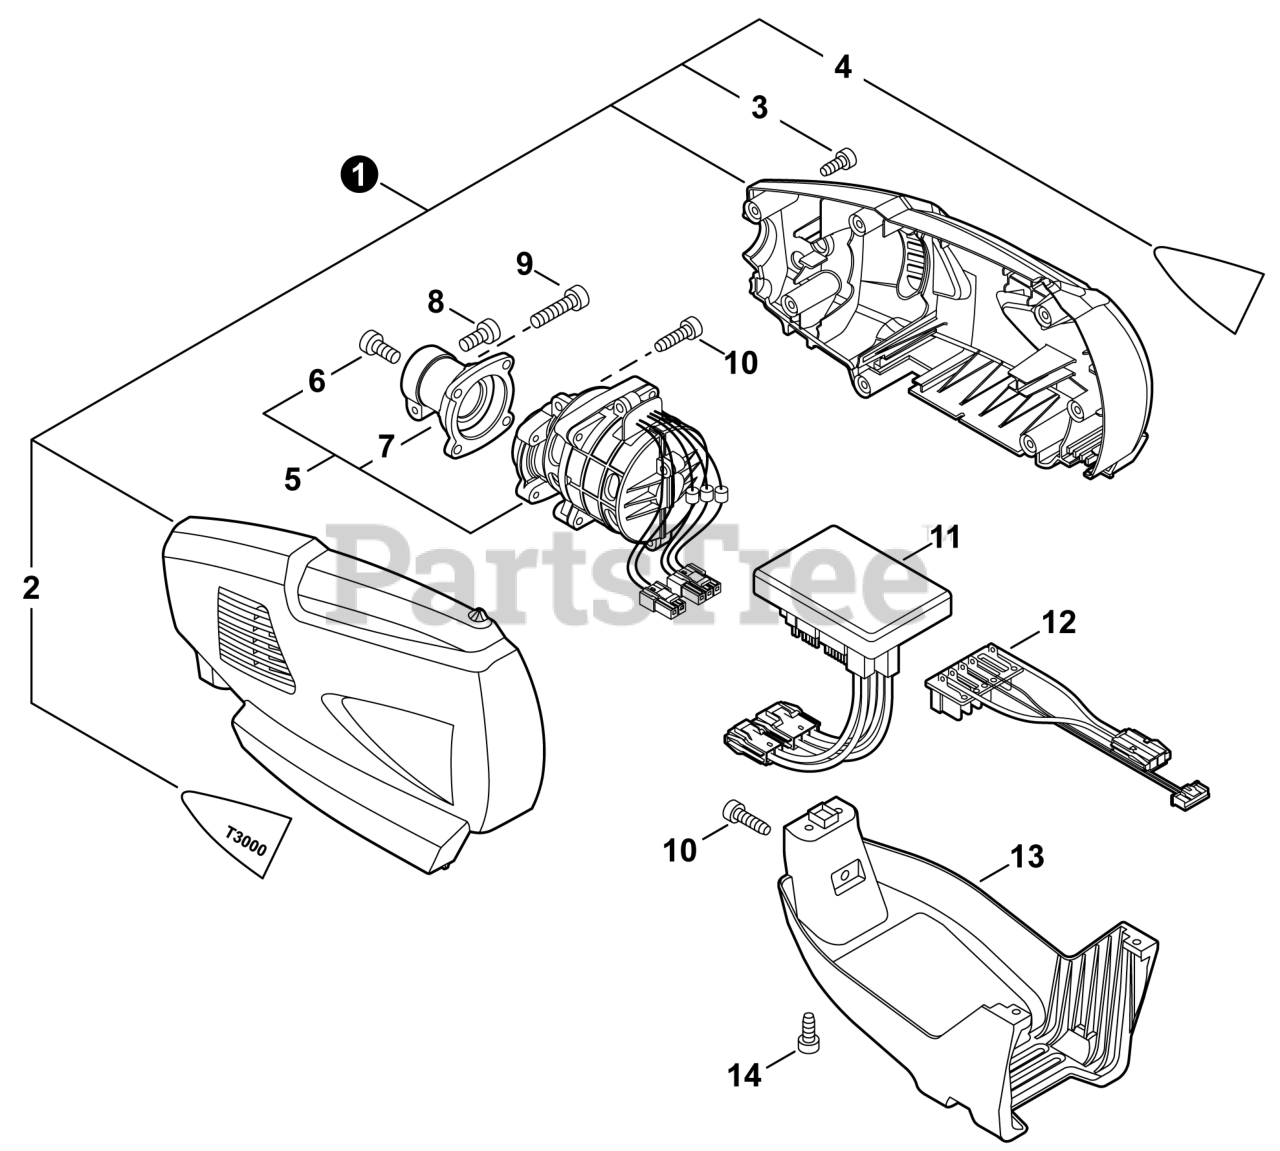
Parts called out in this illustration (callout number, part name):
1	COVER SET, ENGINE
2	LABEL - MODEL T3000
3	BOLT, TORX 4x16
4	LABEL - MODEL T3000
5	MOTOR ASSY
6	BOLT, TORX 5x16
7	HOLDER, MAIN PIPE
8	BOLT, TORX 5x10
9	BOLT, TORX 5x25
10	BOLT, TORX 5x20
11	CONTROL BOARD ASSY
12	TERMINAL, LEAD
14	BOLT, TORX 4x16
